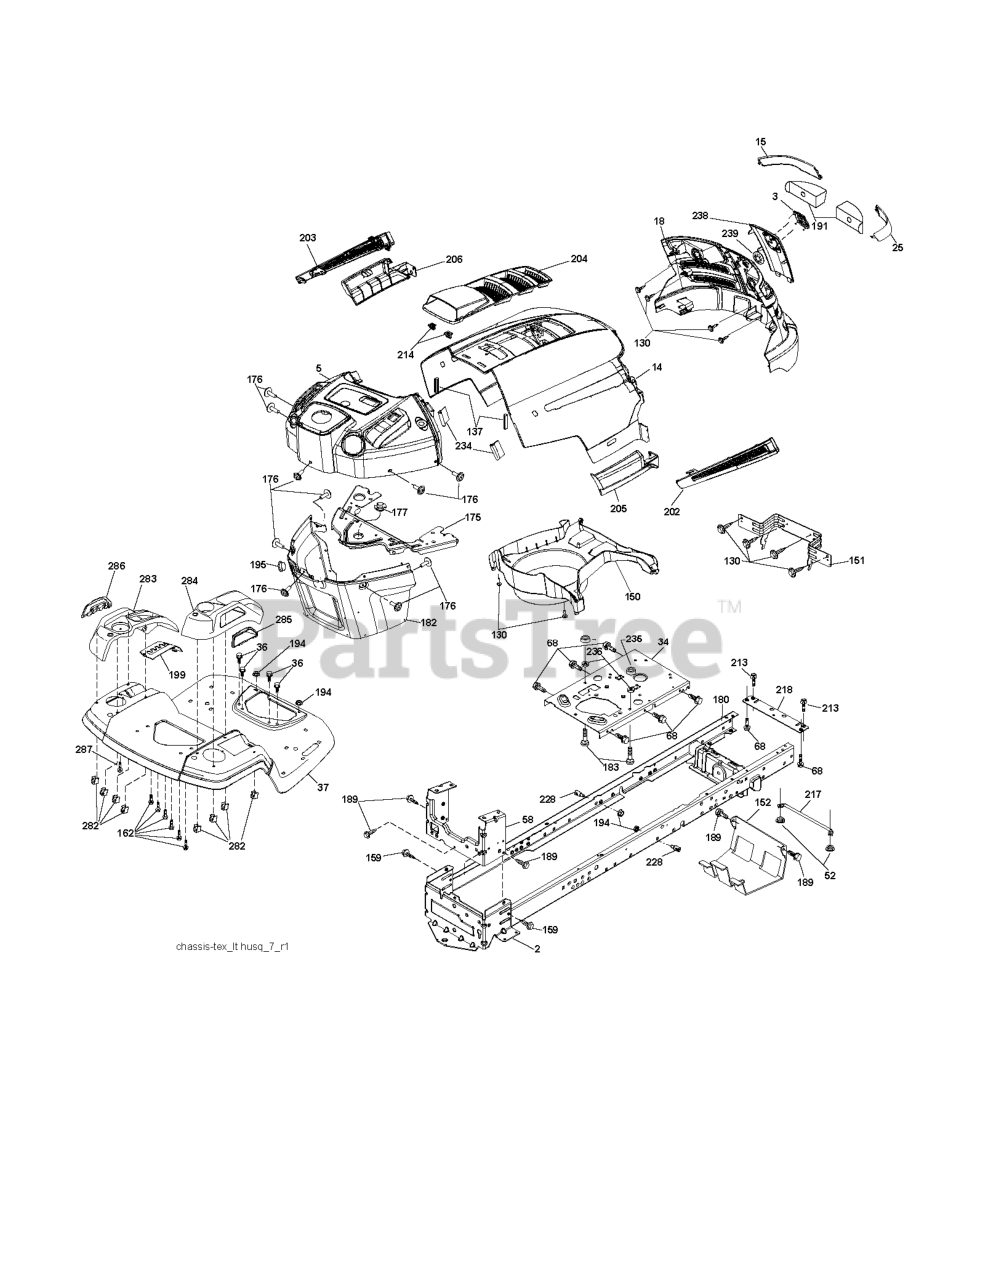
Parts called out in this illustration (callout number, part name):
2	DRAWBAR.LOWER.2PC.18/22
3	RP LOGO
5	DASH
14	HOOD
15	LENS.HUSQVARNA LT.LH
18	RP GRILLE/LENS ASM.
25	LENS.HUSQVARNA LT.RH
34	PLATE.ENGINE.WELDED.CHASSIS
36	SCREW 5/16"
37	RP FENDER.TLT.FS.W/CPH.422
52	LOCKNUT
58	DRAWBAR UPPER 2PC SMALL FENDER
68	Screw 5/16-18 x 1/2 Hex, Self Tapping 5/16-18 x 1/2
130	SCREW
137	BUMPER DASH
151	BRACKET PIVOT
152	SHIELD.BROWNING.W/TEX
159	SCREW, 3/8-16X3/4
162	SCREW.HI-LO.CONSOLE
175	CROSSMEMBER
176	SCREW.#10-24X5/8.RN.QU
177	BUSHING STEERING
180	CHASS.WLDMNT.TL.12GA/2P.48/54
182	DASH.LOWER.PREDATOR LT
183	BOLT.5/16-18X1-1/4 FULL.THREAD
189	SCREW
191	INSERT REFLECTIVE
194	NUT LOCK HEX FLANGE 5/16-18
199	PLATE.DECK.LIFT.HUSQ.LT
202	VENT SIDE HOOD RH
203	VENT SIDE HOOD LH
204	VENT TOP HOOD
205	SKIRT SIDE RH
206	SKIRT SIDE LH
213	BOLT
214	CLIP.RETAINER.TINNER.
217	ROD.PIVOT.HOOD
218	X-PIECE.HOOD.STOP.NON/
228	STUD.FASTNER.W/ANTI-ROTATE
234	BUMPER.HOOD.TEX.HUSQVARNA
235	SPACER FENDER
236	NUT.CENTERLOCK.5/16-
238	TRIM
282	CLIP.RETAINER.CONSOLE.LT.HUSQ
283	CONSOLE.DECK.LIFT.HUSQ.N/FR.GR
284	CONSOLE.SHFT.HYD,HUSQL
285	CONSOLE INSERT RH
286	CONSOLE.INSRT.LH.HUSQ.LT.BLACK
287	SCREW 1/4X20
